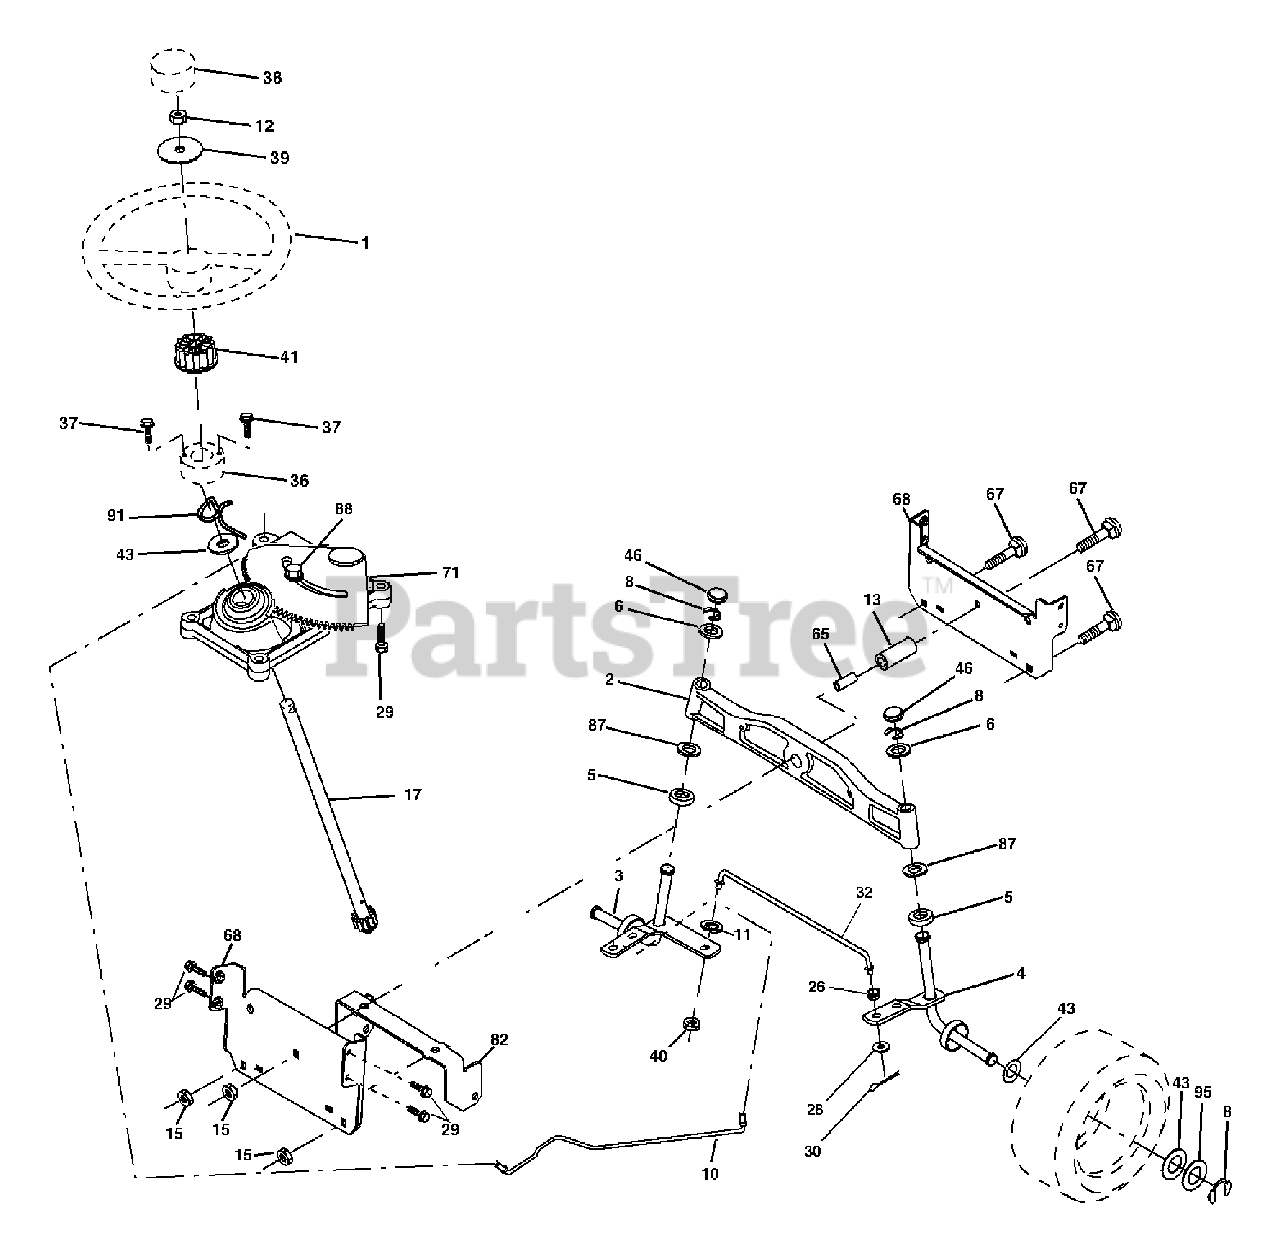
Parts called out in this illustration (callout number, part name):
1	Wheel Steering
2	Axle Asm Cast Iron LT
3	Spindle Asm LH
4	Spindle Asm RH
5	Bearing Race Thrust Harden
6	Washer 25/32 x 1-5/8 x 16 Ga.
8	Ring Klip #t5304-75
11	Washer Lock Hvy Hlcl Spr 3/8
12	Nut Hex Jam Toplock 1/2-20 unf
13	Spacer Brg Axle Front
15	Nut Hex Flange Lock
17	Shaft Asm Steering
26	Bushing Link Drag
28	Washer 13/32 x 7/8 x 16 Ga.
29	Screw 3/8-16 x .75
30	Pin Cotter 1/8 x 3/4
36	Bushing Strg
38	Insert Cap Strg Wh
39	Washer 9/16 ID x 2-3/8 OD x 12 Ga.
40	Crownlock nut
41	Adapter Wheel
43	Washer 25/32 x 1 1/4 x 16 Ga.
44	Extension Steering Shaft
46	Cap Spindle Fr Top Blk
65	Spacer Brace Axle
67	Bolt RDHD SANK 3/8-16 x 2 1/4
68	Axle, Brace
71	Steering Asm
82	Bracket Susp Chassis Front
87	Washer Flat .781 x 1-1/2 x .14
88	Bolt Shoulder 7/16-20 unc
91	Clip Steering
95	Washer Harden .739 x 1.637 x 060
